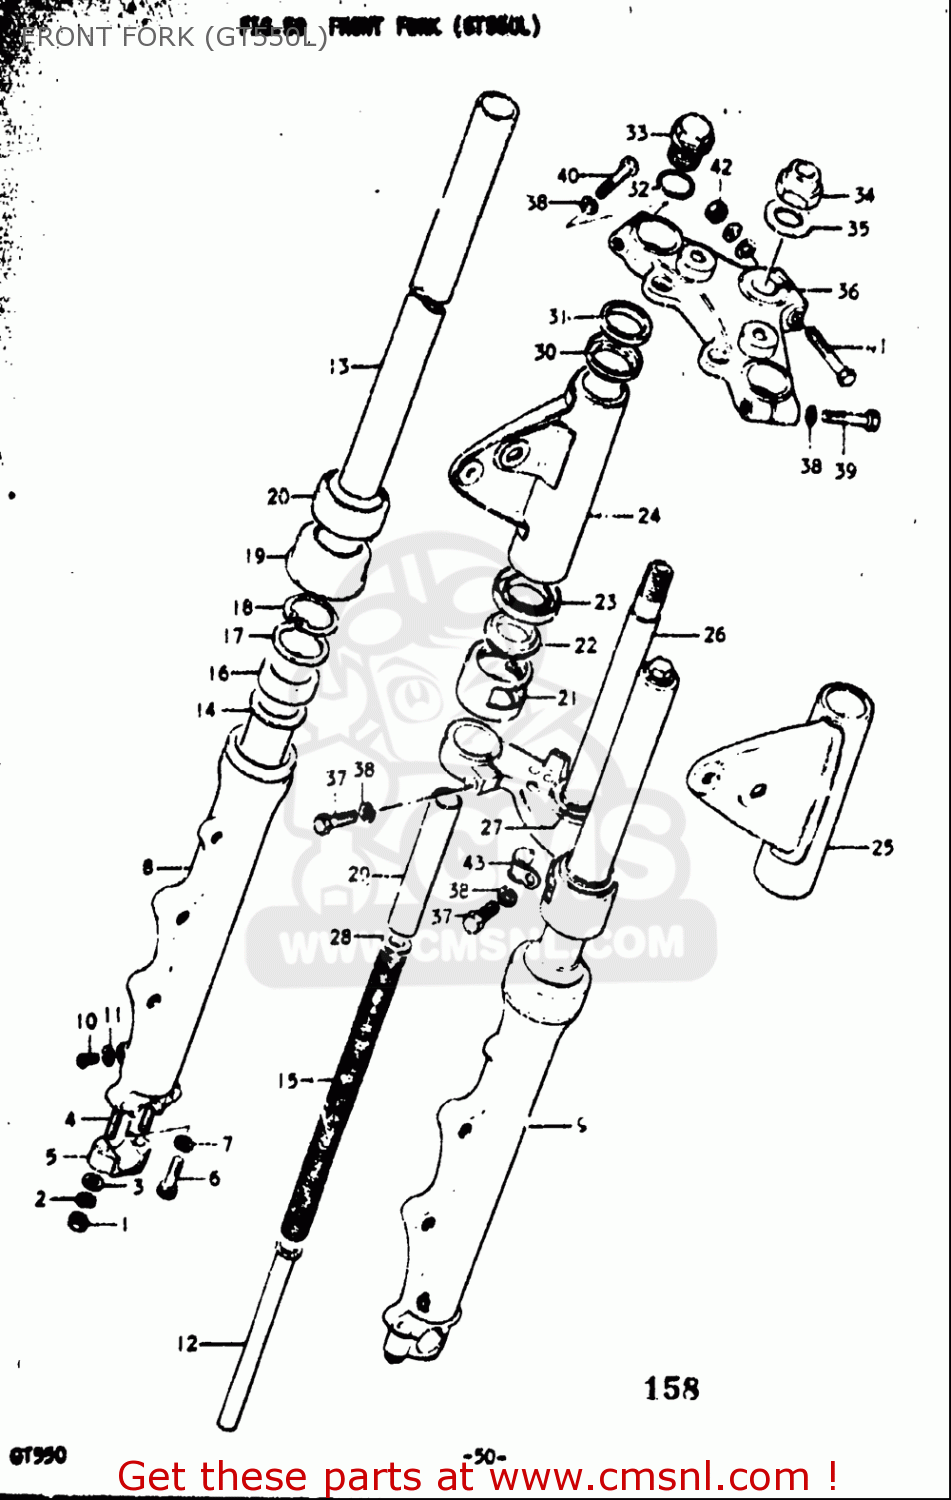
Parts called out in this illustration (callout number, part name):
1	NUT
2	WASHER,LOCK
3	WASHER
4	BOLT,STUD
7	GASKET (NAS)
10	SCREW
11	GASKET,DRAIN,PLUG (NAS)
15	SPRING,FRONT
16	SEAL,OIL
23	GUIDE
27	RACE,STEERING OUTER LWR
30	GUIDE
32	O-RING,FORK FITTING BOLT
33	CAP,FORK INNER TUBE
34	NUT
37	BOLT
38	WASHER,LOCK
39	BOLT
41	BOLT
42	NUT
